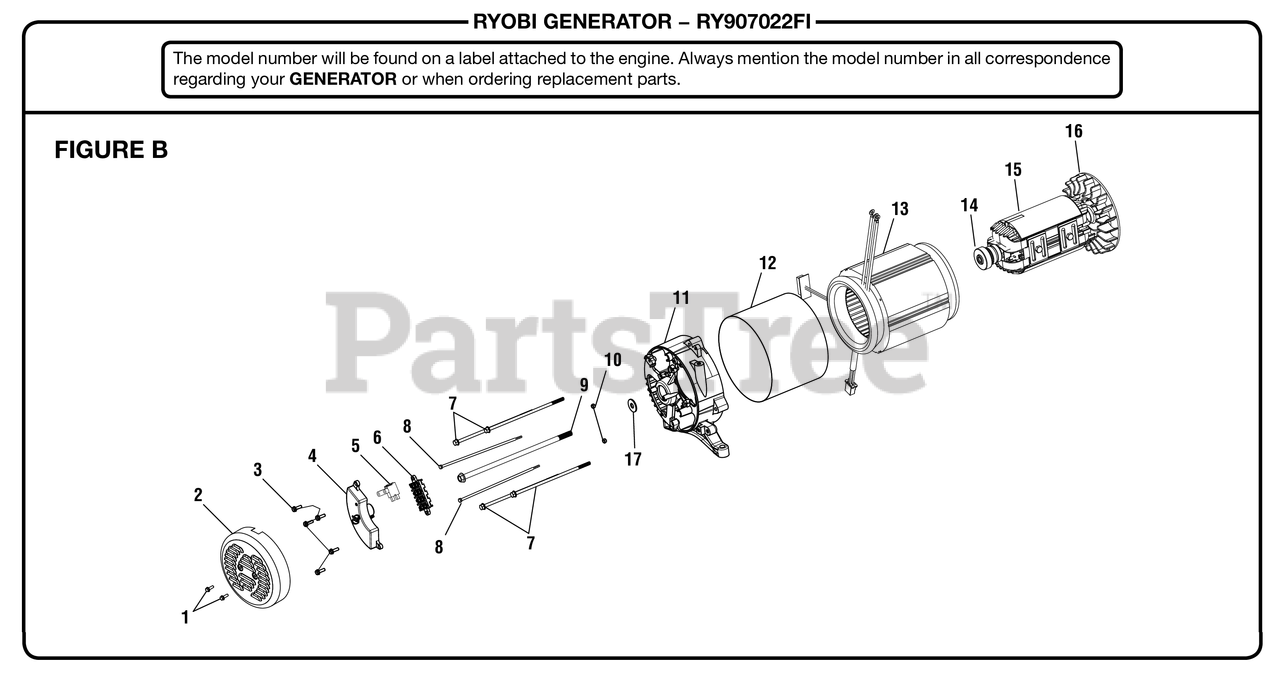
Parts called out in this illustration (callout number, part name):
1	Bolt (M5 x 12 mm, Hex Flange Hd.)
2	Brush Cover
3	Bolt (M5 x 16 mm, Hex Flange Hd.)
4	Automatic Voltage Regulator (5000 Watt)
5	Brush Assembly 190 mm
6	Terminal Block
7	Stator Bolt
8	Bolt (M5, Hex Hd.)
9	Bolt (M10 x 280 mm)
10	Hex Nut (M5)
11	Bearing Housing'
12	Generator Head Cover
13	Stator Assembly
14	Ball Bearing (190 mm)
15	Rotor Assembly
16	Fan (190 mm)
17	Washer (ID10.5 x OD25 x 2t)
